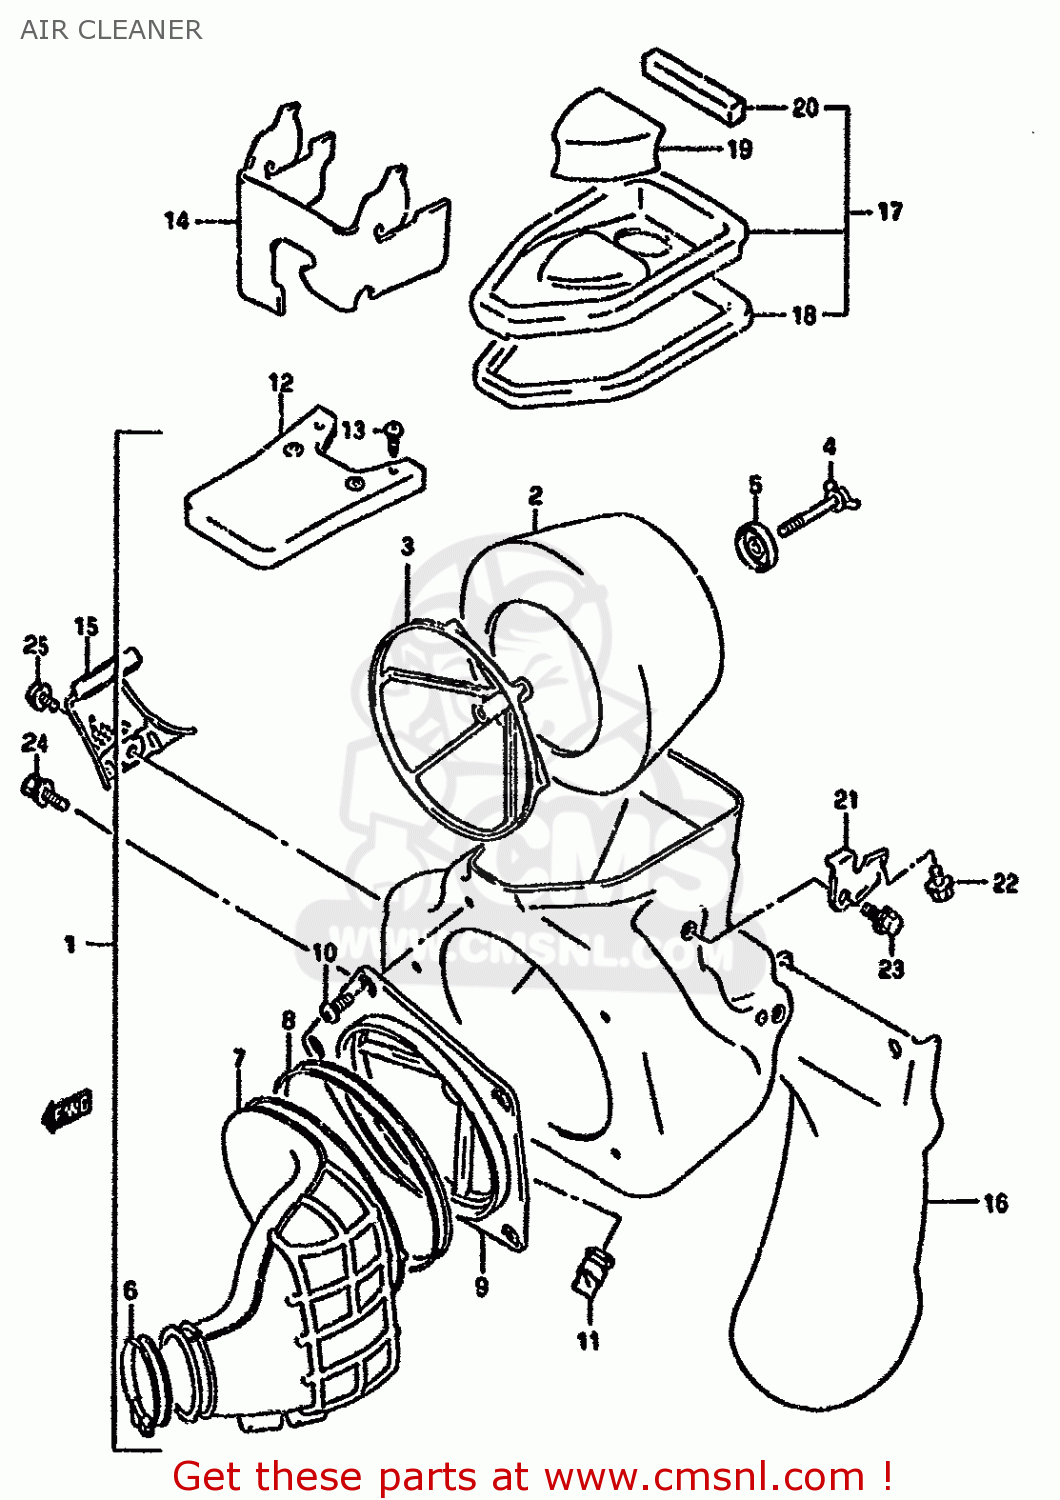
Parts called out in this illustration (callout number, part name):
1	CLEANER ASSY,AIR
2	FILTER ASSY
3	HOLDER,FILTER
4	BOLT,WING
5	WASHER,AIR CLEANER
6	CLAMP
7	TUBE,OUTLET
8	CLAMP
9	BASE,FILTER
10	SCREW
11	CAP,DARIN
12	GUARD,MUD UPR
13	SCREW
14	GUARD,MUD
15	COVER,AIR CLEANER
16	GUARD,MUD
17	CAP,AIR CLEANER
18	GASKET,CAP
19	CUSHION,A T:28
20	CUSION,B T:15
21	BRACKET,AIR CLEANER
22	BOLT
23	BOLT
24	BOLT
25	SCREW
